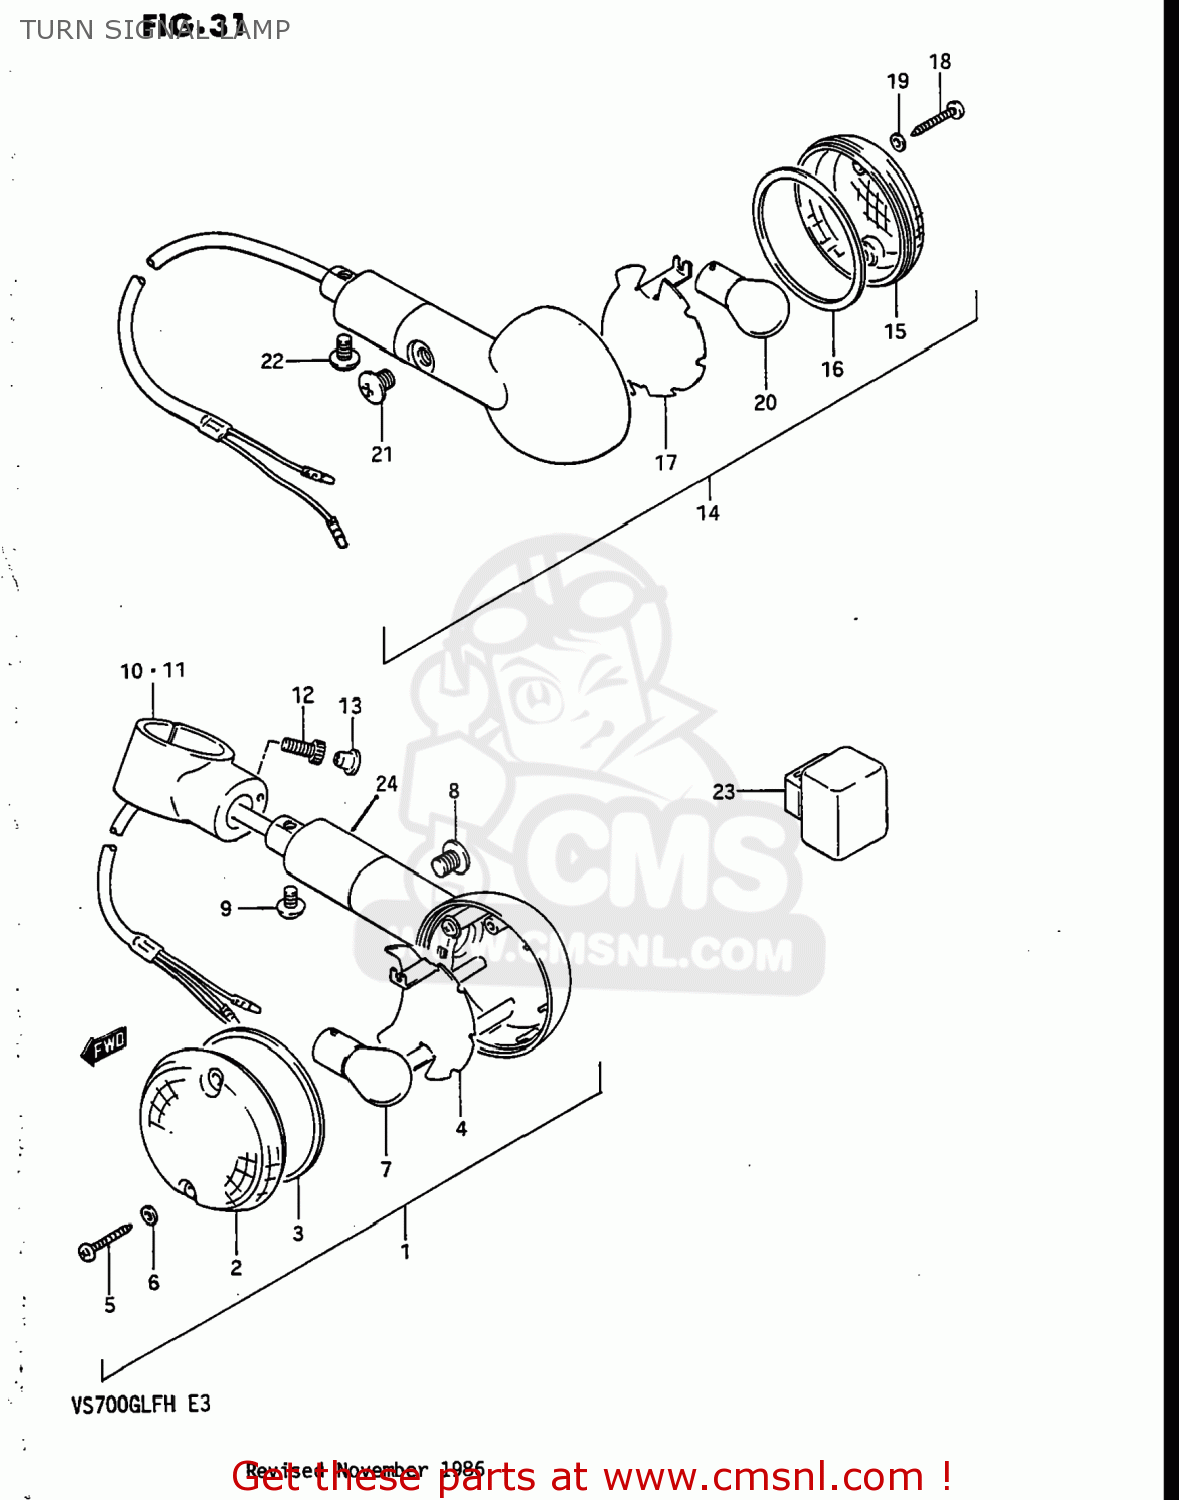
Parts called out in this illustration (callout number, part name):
1	LAMP ASSEMBLY,FRONT TURN SIGNAL
2	LENS
3	GASKET (NAS)
4	REFLECTOR
5	SCREW TAPP.
6	GASKET (NAS)
7	BULB(12V23/8W,TOKAI DENSO)
8	SCREW
9	SCREW
10	BRACKET,FRONT TURN SIGNAL
11	BRACKET,FRONT TURN SIGNAL
12	BOLT
13	CAP(OD:10)
14	LAMP ASSEMBLY,REAR TURN SIGNAL
15	LENS
16	GASKET (NAS)
17	REFLECTOR
18	SCREW ,4X25
19	GASKET (NAS)
20	BULB(12V23W,STANLEY,A4577A)
21	SCREW
22	SCREW
23	RELAY ASSEMBLY,TURN SIGNAL
